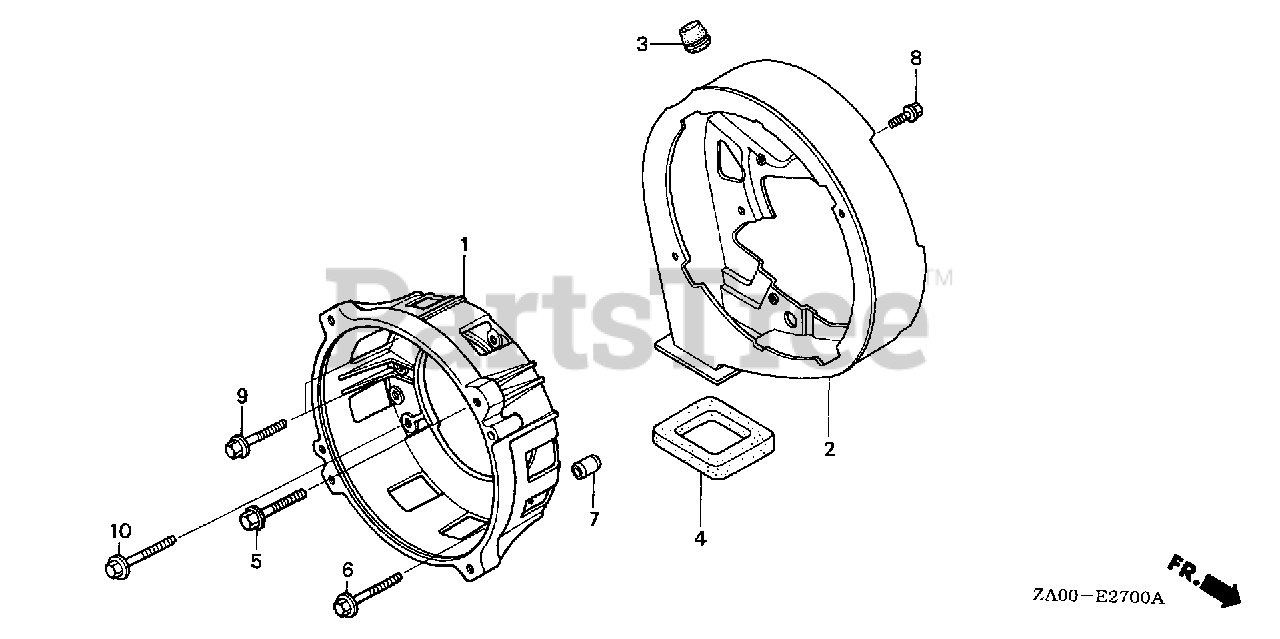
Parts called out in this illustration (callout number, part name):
1	HOUSING, FR.
2	COVER, DUCT
3	GROMMET, DUCT COVER
5	BOLT, FLANGE (8X32)
6	BOLT, FLANGE (8X40)
7	PIN A, DOWEL (10X14)
8	BOLT, FLANGE (6X12)
9	BOLT, FLANGE (8X32)
10	BOLT, FLANGE (8X40)
